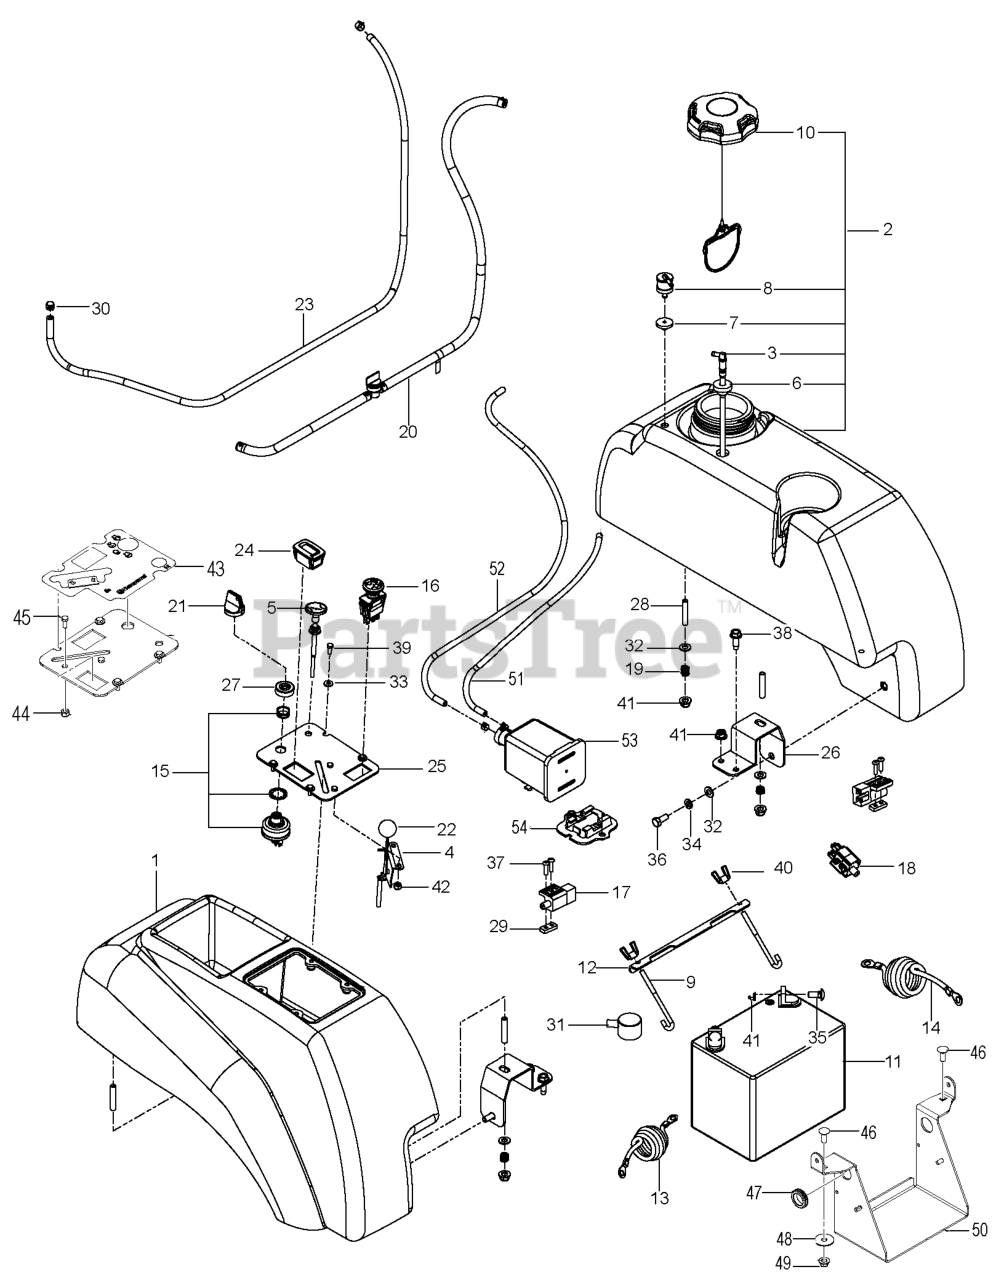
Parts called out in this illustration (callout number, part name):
1	FENDER CONSOLE
3	FITTING, FUEL
4	THROTTLE CONTROL W/BALL KNOB
4	THROTTLE CABLE
5	CABLE, CHOKE
6	RUBBER GROMMET
7	GROMMET, CHECK VALVE
8	VALVE.FUEL.CHECK
9	Hooks
9	HOOK, "J"
10	CAP, FUEL
11	BATTERY, 12 V 330 AMP
11	BATTERY WET NOT SELLABLE
12	Brackets
12	BRACKET, BATTERY MOUNT
13	CABLE.BATT.SOLENOID.MZ.RED.25"
14	CABLE.GROUND.BATT.MZ.BLACK.39"
15	SWITCH, IGNITION, INDAK
16	RP SWITCH.PTO.TERMINAL.STD.RED
17	SWITCH INTERLOCKT
18	SWITCH.INTRLCK.CLUTCH.
18	SWITCH, BRAKE 3P
20	FUEL.HOSE.SHUT.OFF.ASM.10".26"
20	FUEL.HOSE.SHUT.OFF.ASM.10".10"
21	KEY, IGNITION
22	KNOB.ROUND.BALL.BLACK
23	HOSE.3/16".VAPOR.LINE.64"LGTH
24	GUAGE.SRVCMNDR.HRMTR.
25	PLATE.PNT.CONSOLE.MZ.EDIP
26	SUPPORT, TANK, BLK
27	CAP IGNITION NUT
28	STUD, 5/16C
29	PLATE NUT ZTR
30	CLAMP, HOSE
31	COVER.TERMINAL.BATTERY
32	WASHER
34	WASH.5/16.SLW.ZD
35	RP BOLT 5/16-18 X3/4 ZN/YEL GR
35	GSPW Bolts
36	BOLT.FIN.HEX.5/16-18X3/4
37	SCR #10-24 X .75 SKT HD BLK
38	SCREW
39	HCS #10-24 X 1/2
40	WING NUT 1/4
41	NUT HEXAGON FLANGE 5/16-18 ST
41	5/16-18 NYLOC FLANGE NUT
42	NUT 10-24 NYLOC
43	DECAL, CONSOLE HUS
44	Hardware
45	Screws
46	Bolts
47	RUBBER GROMMET
48	Washers
49	GSPW Nuts
50	BRACKET BATTERY BLACK MS-431
51	HOSE.3/16".VAPOR.LINE.36"LGTH
52	HOSE.3/16".VAPOR.LINE.27"LGTH
53	CANNISTER, CARBON
54	BRACKET, CANISTER
